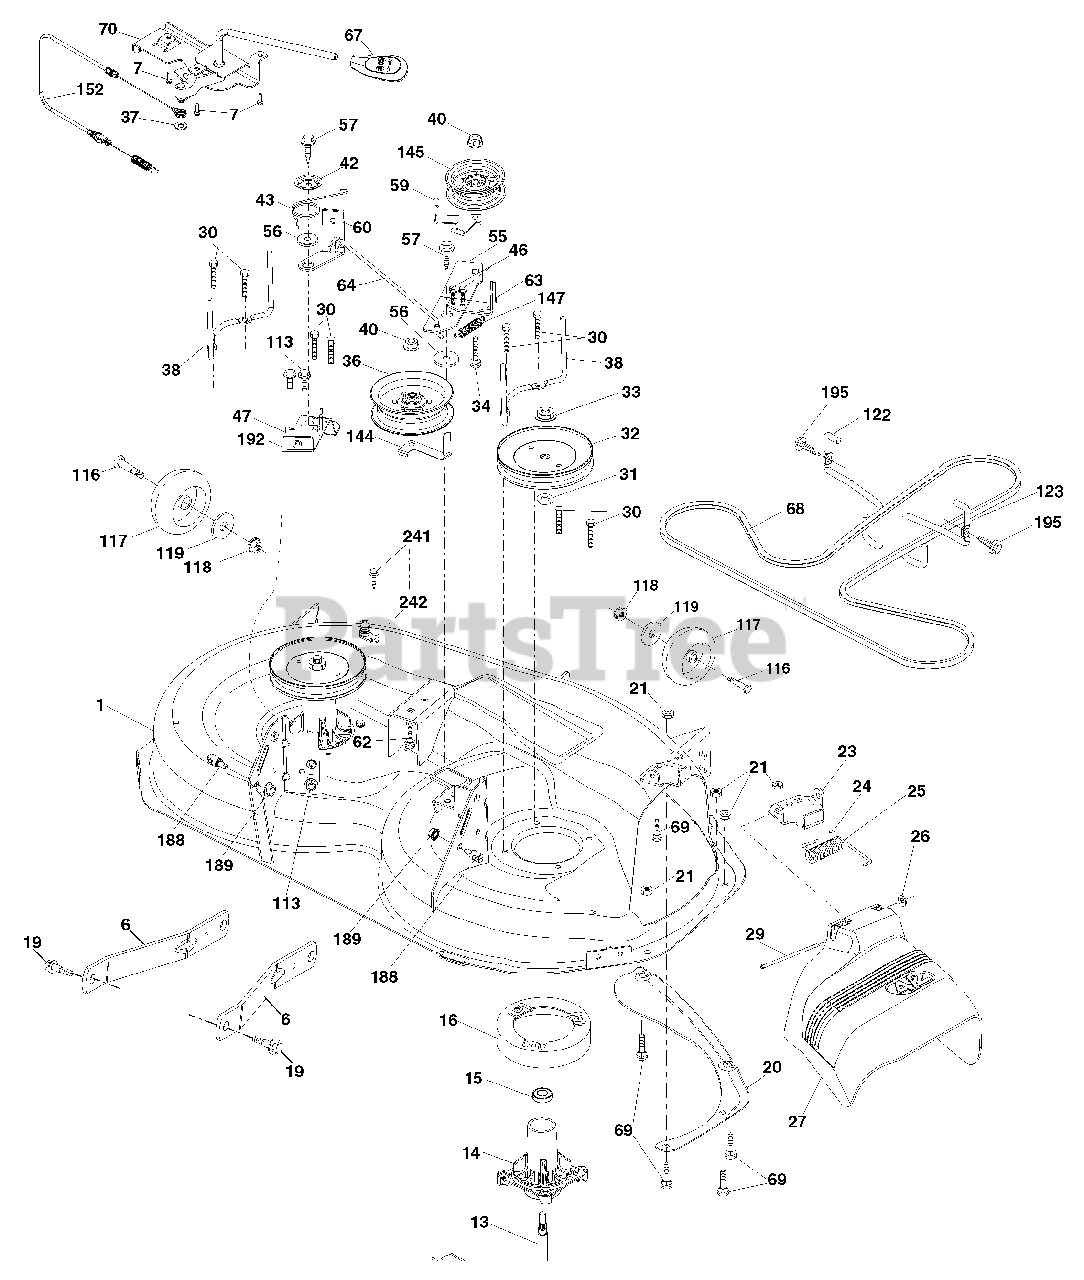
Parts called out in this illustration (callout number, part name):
1	Mower Housing
6	Arm Suspension
7	Screw #10 x 0.750 BOS Thread
8	Bolt/Washer Asm 7/16-20 unf
8	Blade, 42" Mulching Premium
11	Blade, 42" Hi-Lift
11	Blade, 42" Mulching Std
13	Shaft Assembly, Mandrel
14	Housing, Mandrel
15	Bearing, Ball, Mandrel
16	Stripper, Mower Deck
19	Bolt, Shoulder
20	Baffle, Vortex
21	Nut, Crownlock 5/16-18 unc
23	Bracket, Deflector
24	Cap, Sleeve
25	Spring, Torsion, Deflector
26	Nut, Push
27	Shield, Deflector
29	Rod, Hinge
30	Screw Thdrol Rolling Wsh Hd
31	Washer, Spacer
32	Pulley, Mandrel
33	Nut, Toplock, Flanged
34	Bolt Carr Sh. 3/8-16 x 1-1/2 Gr. 5
36	Pulley, Idler 4.50 RAW
37	Washer 13/32 x 13/16 x 16 Ga.
38	Keeper Belt LH Mandrel
40	Nut, Lock Flg. 3/8-16 unc
42	Spring Torsion Retainer
43	Spring Torsion Brake
46	Screw Thd Roll 1/4-20 x 5/8
47	Bracket Clutch Cable
55	Arm, Idler
56	Spacer, Retainer
57	Screw Hexwsh Thd 3/8-16 x 1
59	Guard, Tuv Idler (94)
60	Arm Brake Mower
62	Bolt Rdhd Sqnk 3/8-16 unc x 2
63	Arm Brake Mower
64	Linkage Brake
67	Handle, Clutch Cable
68	V-Belt
69	Bolt Rdhd Sqnk 5/16-18 x 5/8
70	Clutch Asm. Manual
113	Screw 5/16-18
116	Bolt
117	Wheel Gauge
118	Nut Lock 3/8-16 unc
119	Washer 3/8-7/8 x 14 Ga.
122	Keeper Belt Eng. LH
123	Keeper Belt Eng. RH
144	Keeper Belt
145	Pulley Idler Primary
147	Spring Return
152	Cable Clutch Manual w/Spr.
188	Stud Fastener
189	Nut Lock Hex Flange
192	Bracket Brake Stand LH
195	Screw Hexwsh Thdr 3/8-16 x 3/4
241	Vis
242	Port, Washout
242	Mandrel Assembly
242	Replacement Mower, Complete
